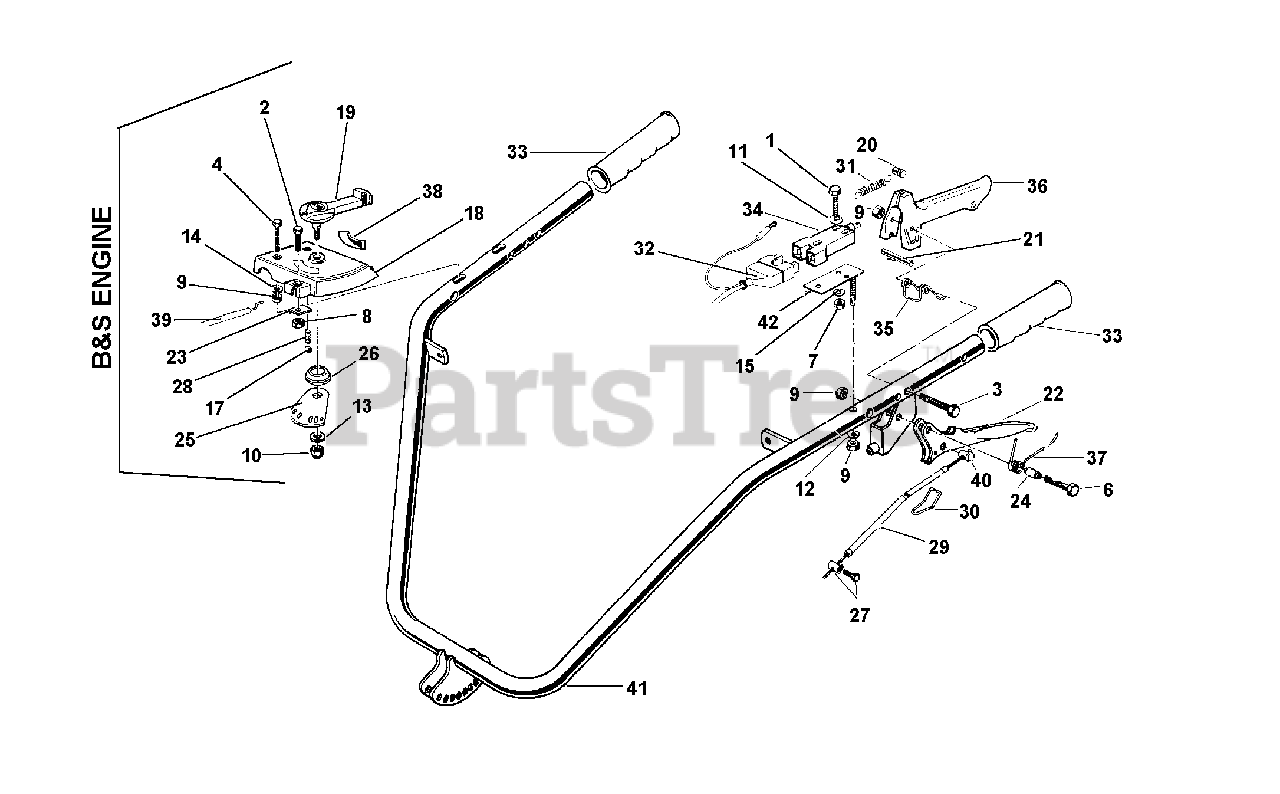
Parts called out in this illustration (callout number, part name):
1	SCREW TE M4 X 25
2	SCREW M5 X 10
3	SCREW TE M6 X 45
4	SCREW M6 X 40
5	SCREW TE M8 X 40
6	SCREW M6 X 25
9	NUT, SELF LOCKING M6
10	NUT, SELF LOCKING M8
11	FLAT WASHER 4.3
12	FLAT WASHER 6.4 X 12.5
13	FLAT WASHER 13
14	LOCK WASHER 6.4
15	LOCK WASHER 4.3
16	LOCK WASHER 8.4
19	THROTTLE LEVER
21	LEVER STOP FOR MOTOR STOP
22	CLUTCH LEVER
24	LEVER SPACER
25	THROTTLE LEVER
27	CLAMP, CABLE
29	CABLE, CLUTCH
31	MOTOR STOP SPRING
32	MOTOR STOP CABLES
34	STOP SWITCH
35	MOTOR STOP LEVER SPRING
36	MOTOR STOP LEVER
37	LEVER SPRING
38	GAS DECAL FOR ENGINE
39	THROTTLE CABLE
42	STOP SWITCH SUPPORT
